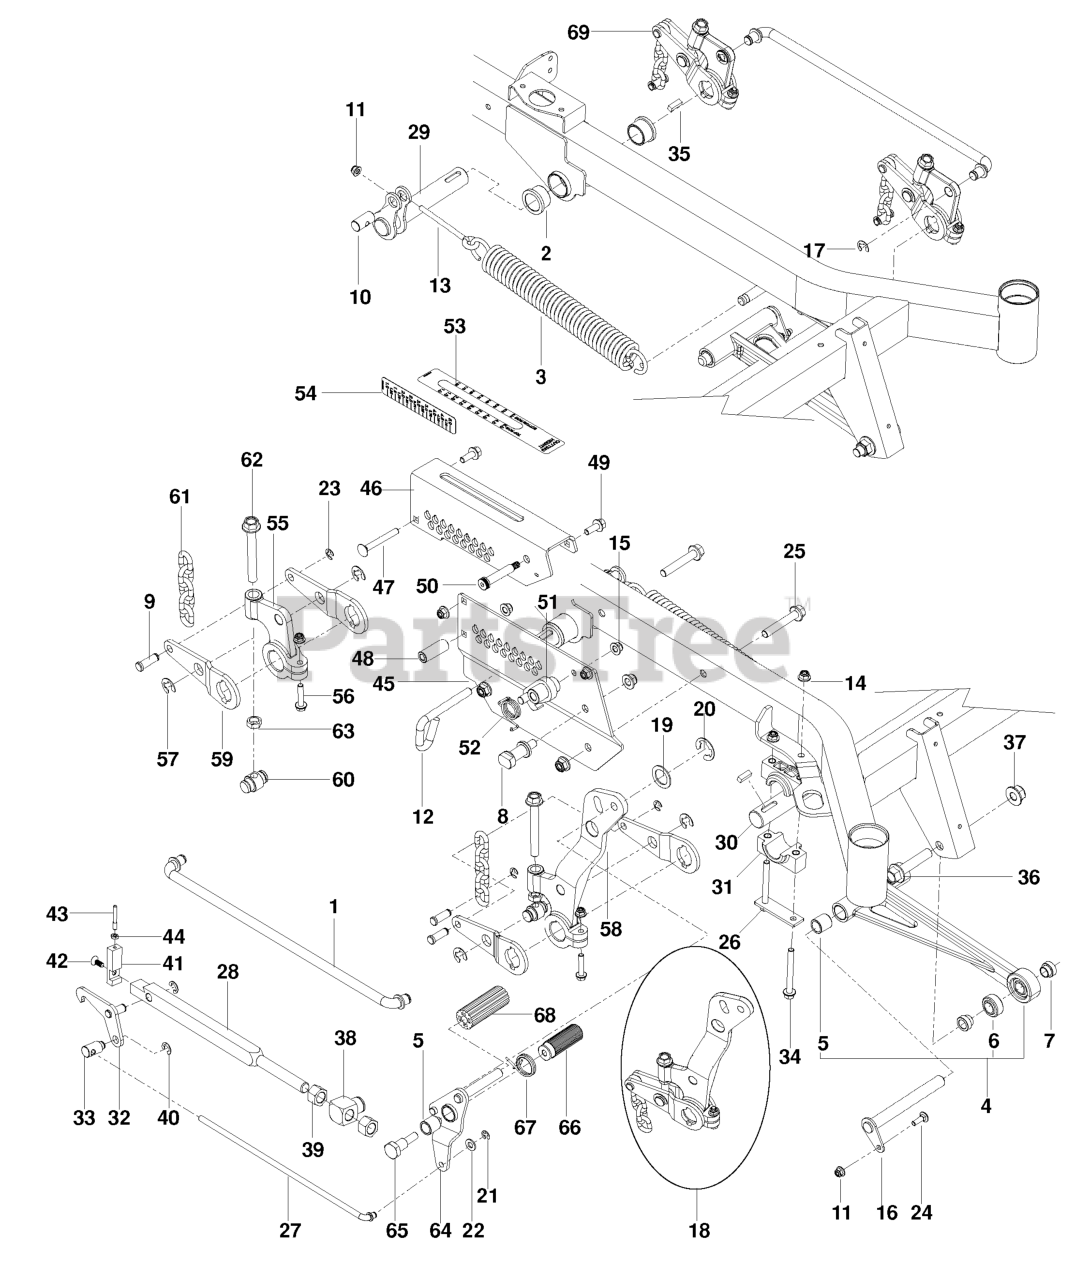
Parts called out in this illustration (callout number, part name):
1	ROD, LIFT
2	BUSHING, FLANGE 1.25 X 1.0
3	SPRING, EXTENSION
4	ASSEMBLY, STRUT
5	BUSHING, SLEEVE 3/4 X 1.0
6	BALL JOINT, 3/4" SWIVEL
7	SPACER, STRUT
8	GUIDE, HEIGHT BAR
9	PIN, 7/16 CLEVIS
10	PIVOT, SPRING
11	5/16-18 NYLOC FLANGE NUT
12	PIN, HEIGHT
13	EYE BOLT 4.5`
14	NUT 3/8-16 HEX FLG NYLOC ZD
15	NUT, 1/2-13 HEX FLG NYLOC ZD
16	PIN, STRUT
17	E-RING 5/8
18	ASSEMBLY, DECK LIFT LEVER
19	MACHINE BUSHING
20	E-RING 1"
21	E RING 3/8"
22	WASHER 3/8 SAE FLAT
23	RING, E, 7/16
24	RHSNB 5/16C X 1
25	HFFS 1/2-13 X 3 GD 5 ZD
26	PLATE, PILLOW BLACK
27	ROD, HEIGHT LATCH
28	BAR, HEIGHT
29	SHAFT, RR LIFT
30	SHAFT, LIFT, FT
31	BLOCK, PILLOW
32	LATCH, HEIGHT WLDMT
33	SWIVEL, HEIGHT LATCH
34	HHFS 3/8-16 X 3.5 GD 5 ZD
35	KEY, 5/16 SQ X 1.0
36	HHFS 5/8-11 X 3.0 GD 8 ZD
37	NUT 5/8-11 FLG NYLOC ZD
38	SWIVEL, HEIGHT BAR
39	NUT 3/4-10 HEX ZD
40	E-RING 1/2 (2 2)
41	CAP, HEIGHT BAR
42	SCREW, 5/16-18 X 3/4 FLAT HEX
43	LINK, INDICATOR
44	NUT 1/4-20 JAM
45	PLATE, INNER HEIGHT, ORANGE
46	PLATE, OUTER HEIGHT ORG
47	3/8-16 X 3` CARR BOLT
48	SPACER, HEIGHT PLATE
49	HHFS 3/8-16 X 1 GRD 5 ZD
50	BOLT, SHOULDER, 1/2 X 2.25
51	LATCH, TRANSPORT WLDMT
52	SPRING, TORSION
53	DECAL, HEIGHT
54	DECAL, HEIGHT
55	ARM, CAST LIFT
56	HHFS 5/16-18 X 1.5 GD 5
57	E RING 3/4
58	ARM, LIFT LEVER
59	ARM LIFT BLK
60	SHAFT, LIFT TRUNION WSL
61	LIFT CHAIN
62	HHFS 1/2-13 X 4 GR 5
63	NUT 1/2 HEX JAM
64	PEDAL, RELEASE WLDMT
65	BOLT, SHOULDER
66	PAD, FOOT PEDAL
67	SPRING, TORSION
68	PEDAL, DECK HEIGHT
69	ASSEMBLY, DECK LIFT CRANK
